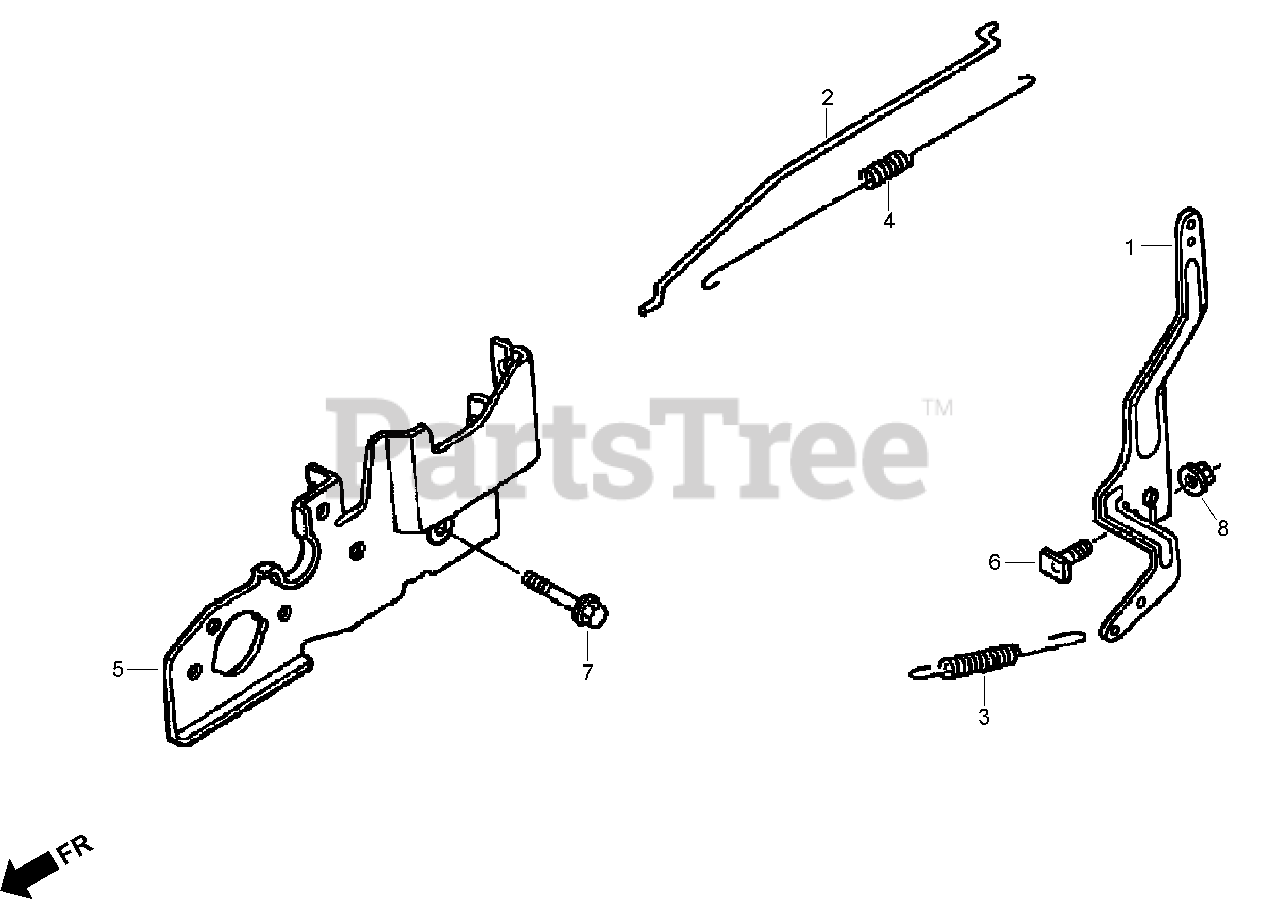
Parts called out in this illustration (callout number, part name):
1	ARM-GOVERNOR
2	ROD-GOVERNOR
3	SPRING-GOVERNOR
4	SPRING-RETURN, THROTTLE
5	BASE-CONTROL
6	BOLT-ARM, GOVERNOR
7	BOLT-FLANGE (6X45) (C T200)
8	NUT-FLANGE (6 mm)
